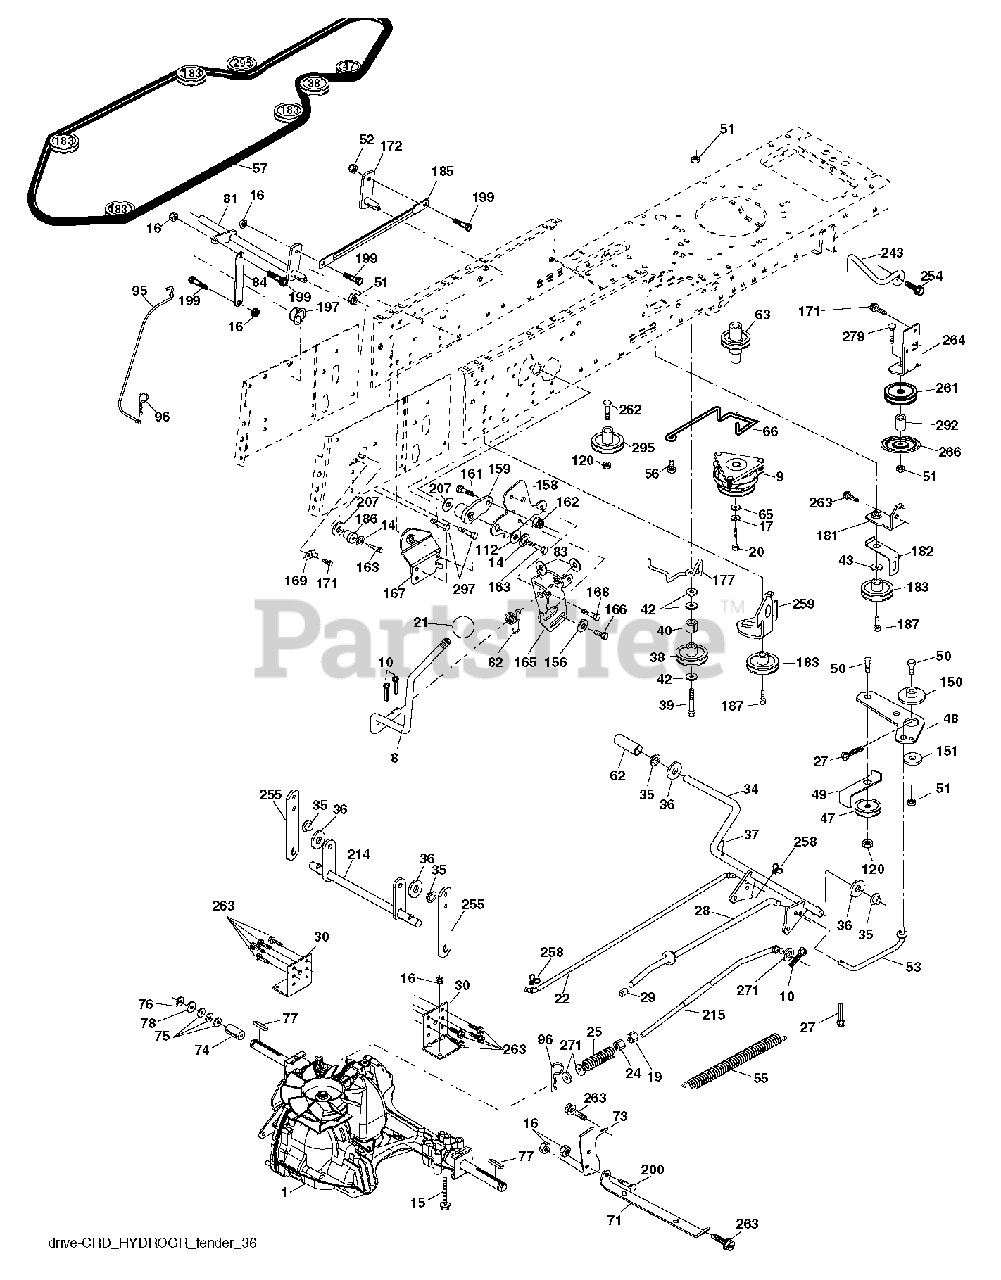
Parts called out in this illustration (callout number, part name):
8	ROD SHIFT FENDER ADJUST LT
10	PIN COTTER
14	LOCKWASHER
15	BOLT HEX 5/16-18 GR 5
16	NUT.71038.31-18.HEX.NYLOCK
19	NUT
20	BOLT HEX 7/16-20X4-1/4"
21	PISTOL KNOB
24	NUT
27	COTTER PIN
28	ROD, PARKING BRAKE
29	PLUNGER CAP
30	BRKT, TRNSXLE MNT 20"
34	SHAFT, FOOT PEDAL
35	BEARING.NYLON
36	WASHER LT
37	DRIVE PIN
38	PULLEY.FLAT
42	WASHER
43	WASHER T
47	IDLER PULLEY
48	BELLCRANK, CLUTCH
49	RETAIN BELT
50	BOLT.3/8-16X1.50
51	LOCKNUT
52	LOCKNUT
53	LINK.CLUTCH.7.66.2005
55	SPRING, RETURN LT
56	SCREW.3/8-16
62	PEDAL COVER T
65	LOCKWASHER
66	KEEPER BELT ENGINE
71	STRAP TORQUE LH HYDRO
73	STRAP TORQUE RH HYDRO
74	SPACER AXLE
76	E-RING LT
77	SQUARE KEY
81	SHAFT ASSY
82	SHIFT SPRING
83	WASHER
96	RETAINER M
112	WASHER LT
120	NUT LOCK FLG 3/8-16 UNC
150	BUSHING.BELLCRANK.GRD.DR
151	WASHER 12/32X2X10GA
156	WASHER.SRRTD.5/16
158	BRACKET.SHIFT.MOUNT
159	HUB.SHIFT
161	BOLT
162	NUT.CROWNLOCK.1/4
163	BOLT
165	BRACKET.PIVOT.LEVER
166	SCREW
167	BRACKET
168	BOLT.SHOULDER.5/16-18X
169	PLATE.FASTENING.CROSS.SHAFT
171	SCREW LT
183	PULLEY.V-IDLER.
187	BOLT.5/16-18X1.25
197	NYLINER SNAP 5/8" ID
199	BOLT SHOULDER 5/16-18 UNC
200	BOLT
207	WASHER NYL
243	BRACKET, ANTI-ROTATION
254	SCREW 3/8-16X1
258	CLIP RETAINER
261	FLAT IDLER PULLEY
263	SCREW, 3/8-16X3/4
264	BRACKET.IDLER
271	WASHER
279	BOLT
295	PULLEY IDLER COMPOSITE
297	SCREW LT.3/8-46X5/8
